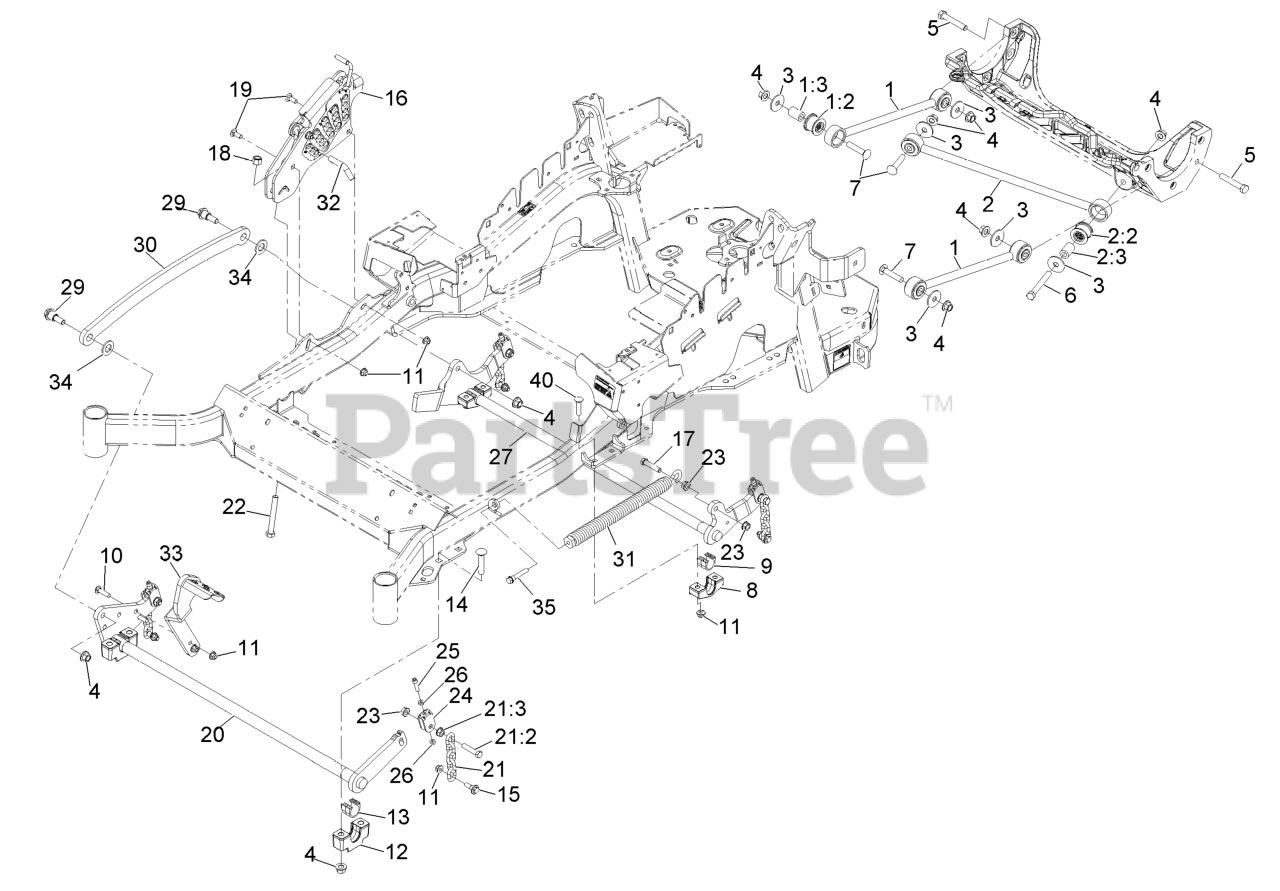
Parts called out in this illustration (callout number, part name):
1	LONG STRUT ASM
1:2	BUSHING-SUSPENSION, RUBBER
2	PANHARD ROD ASM
2:2	BUSHING-SUSPENSION, RUBBER
3	WASHER-THRUST
4	Nut-Lock 1/2-13
5	SCREW-HH
6	SCREW-HH
7	SCREW-CARR
9	BEARING-CROSS SHAFT, REAR
10	SCREW-CARR
11	NUT-HF, NI
12	SUPPORT-CROSS SHAFT, BEARING
13	BEARING-CROSS SHAFT, FRON
14	Bolt-Carriage 1/2-13 X 2 1/2 Spl Neck
15	SCREW-SHOULDER, HHF
16	HOC ASM
17	SCREW-HH
18	NUT-LOCK, NI
19	BOLT-CARR
21	DECK LIFT CHAIN ASM
21:2	SCREW-HH
22	BOLT-TAP
24	YOKE-ADJUST, DECK
25	SCREW-HSH
26	NUT-JAM
27	LIFT-DECK, REAR
29	SCREW-SHOULDER, HHF 1/2-13 X 1.12
30	LINK-LIFT, DECK
31	SPRING-EXTENSION
32	PIN-HOC
33	LEVER-FOOT
34	WASHER-FLAT
35	BOLT-SHOULDER
40	SCREW-CARR
